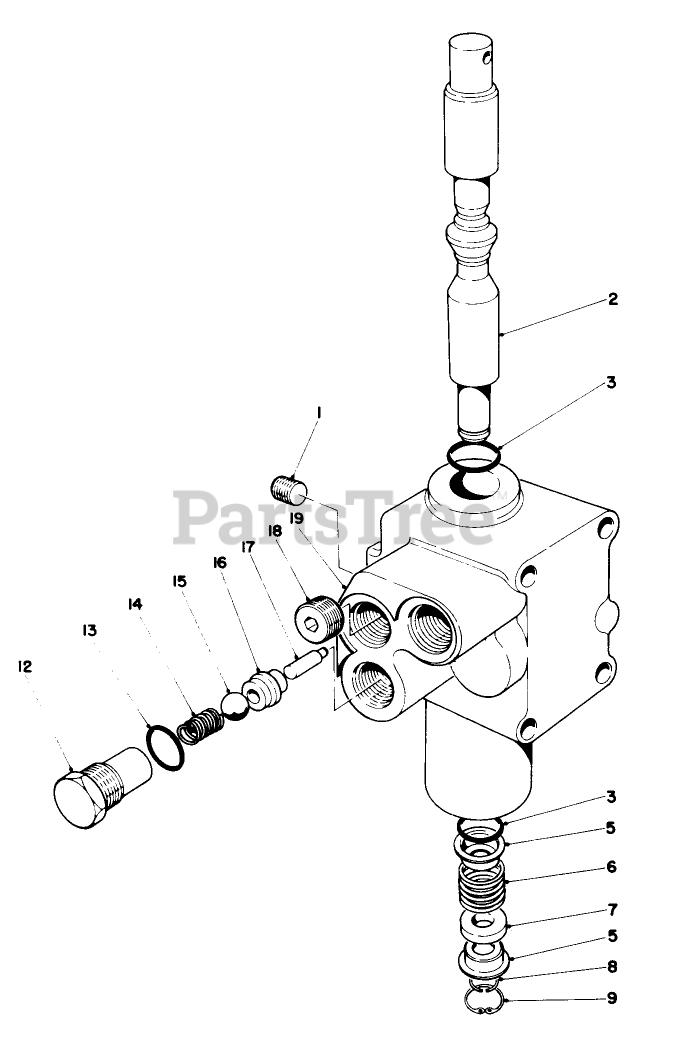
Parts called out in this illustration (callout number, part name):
2	SPOOL
3	O-RING
5	RETAINER
6	SPRING
7	FLOAT SPACER
8	RING-SNAP
9	RING-SNAP
13	O-RING
14	SPRING
16	SEAT-VALVE
